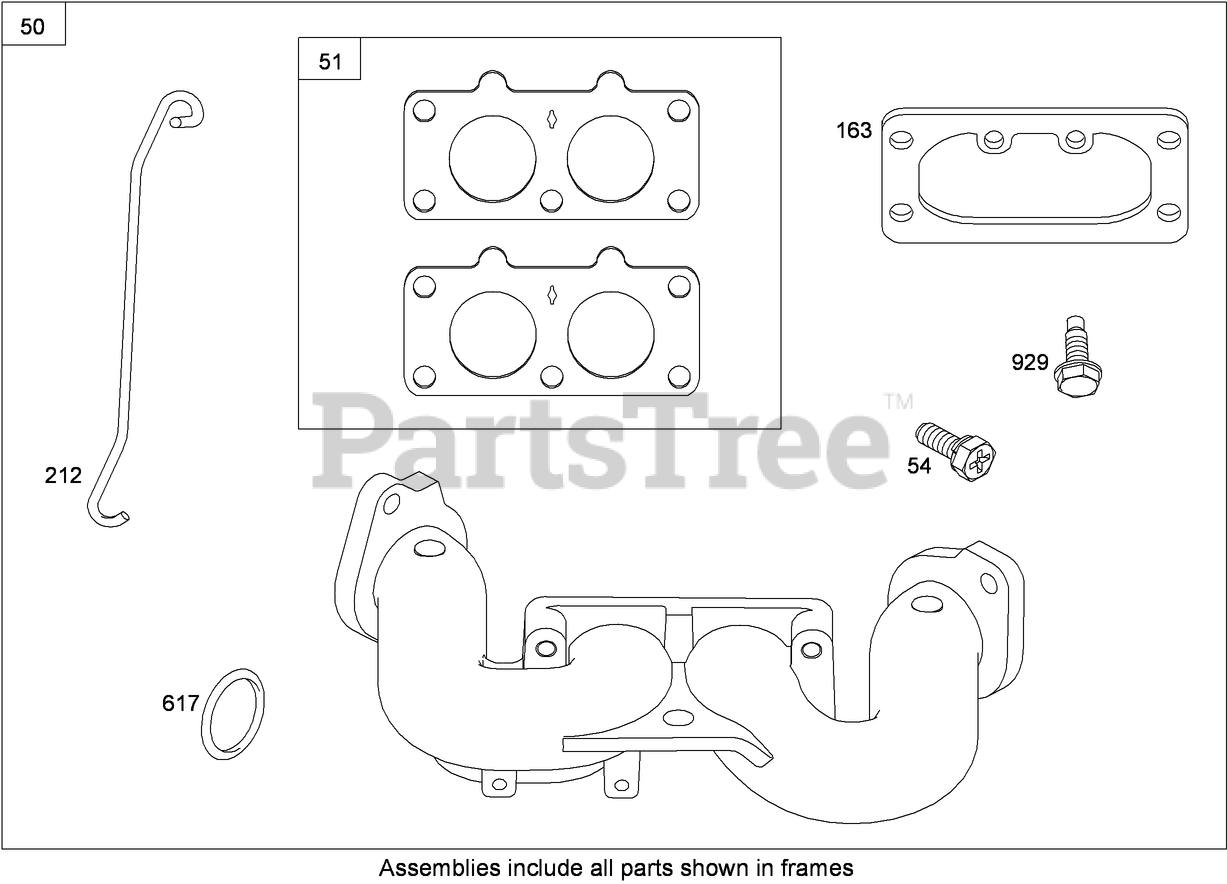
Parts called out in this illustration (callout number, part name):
50	Manifold-Intake
51	Gasket-Intake
54	Screw (Intake Manifold)
163	Gasket-Cleaner, Air
212	Link?Throttle
617	Seal-O Ring (Intake Manifold) (Red)
929	Screw (Choke Control Bracket)
